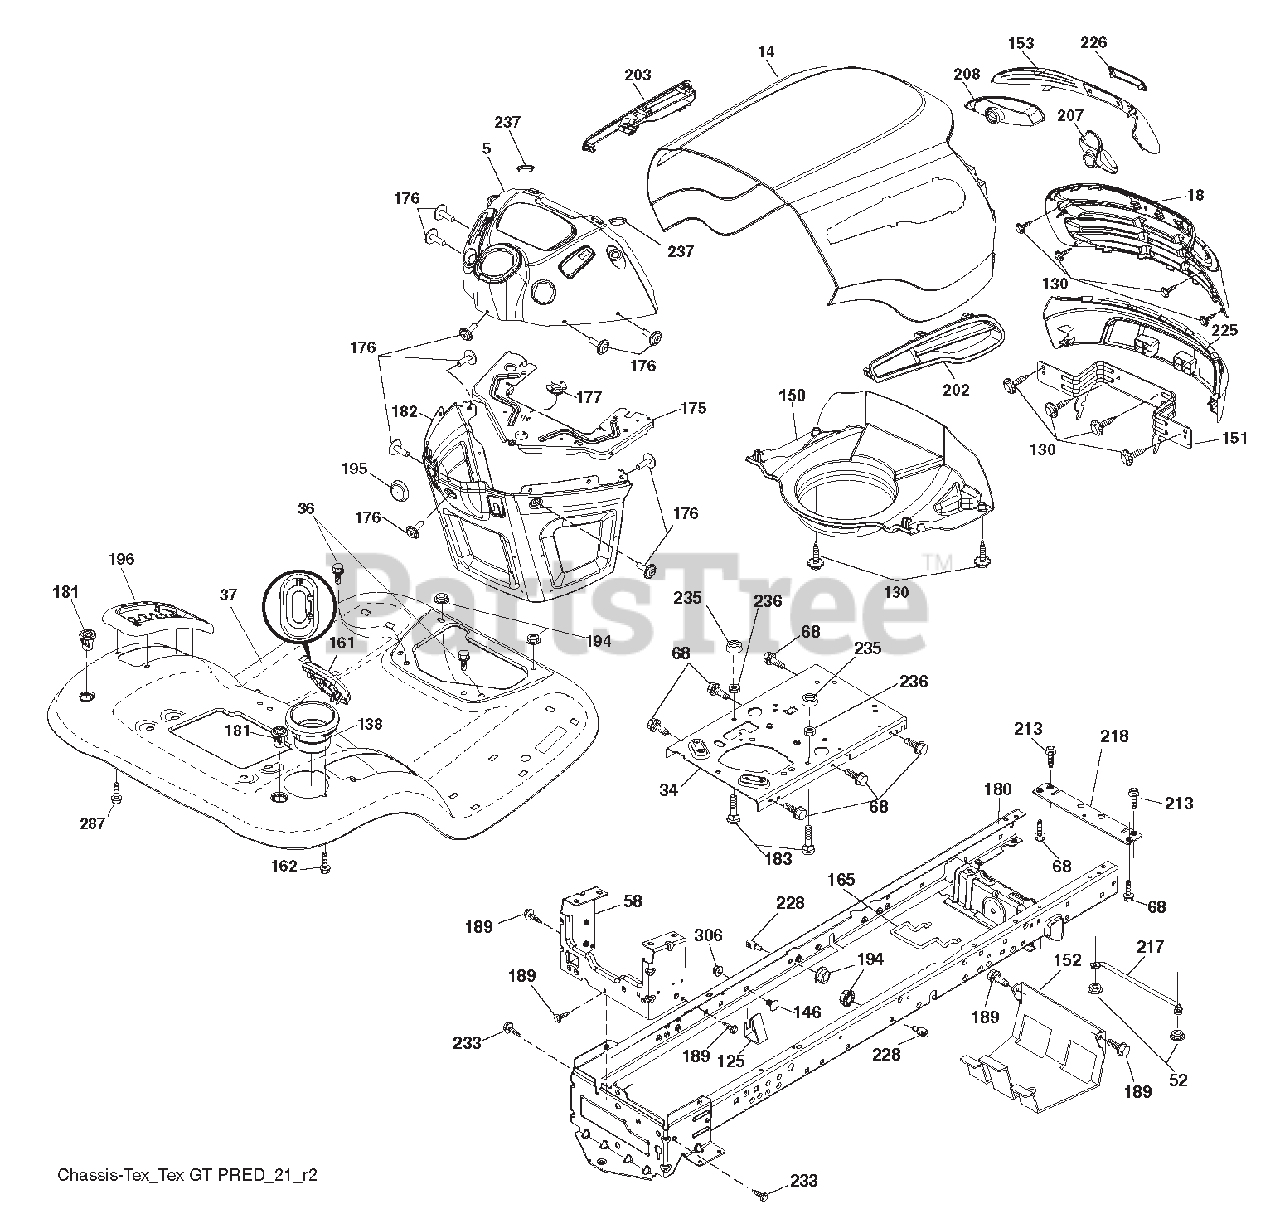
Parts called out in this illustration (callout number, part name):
5	DASH P/L TEX CABLE
18	GRILLE.ELITE.ARIENS.BLACK
34	PLATE.ENGINE.WELDED.CHASSIS
36	SCREW.5/16-18X3/4.SMGML.TAP/R
52	Nut, Hex, Crownlock 5/16-18
58	DRAWBAR.UPPER.2PC.SML.FENDER
68	SCREW.THDROL.5/16-18 X 1/2TYTT
125	CLIP.FUEL.LINE
138	CUPHOLDER TL TEX 428
150	AIR DUCT
151	BRACKET.PIVOT
152	SHIELD.BROWNING.W/TEX
153	LENS.BAR
161	WINDOW FUEL
162	SCREW.HEX.WSH.HI-LO.1/4X1/2UNC
165	SUPPORT.TANK.REAR.W/TEX
175	CROSSMEMBER.LT
176	SCREW.#10-24X5/8.RND.QUDRX.GIM
177	BUSHING.STEERING.YT/GT
180	CHASS.WLDMT.TL.12GA/2PC.18/22"
181	BUSHING MNT FEND CRGO BLK TEX
182	DASH.LOWER.LT.CCS
183	BOLT.FIN.HEX.5/16-18 UNC X1-1/
189	SCREW.5/16-18X3/4.SMGML.TAP/BL
194	Nut, Lock Hex Flange 5/16-18 u
195	PLUG HOLE DASH TOWER
196	CONSLE.ASM.DECK.LFT.BL/RBT.TLT
202	VENT RH
203	VENT.SIDE.LH
207	BEZEL.RH
208	BEZEL.LH
213	BOLT.HEX.HD.1/4-20UNC X 3/4
217	ROD.PIVOT.HOOD
218	X-PIECE.HOOD.STOP.NON/STEALTH
226	ARIENS.LOGO.PLATE
228	STUD.FASTNER.W/'D'ANTI-ROTATIO
233	BOLT.SHOULDER
235	SPACER.FENDER
236	NUT.CENTER LOCK.5/16-18 UNC
237	PLUG.MOUNT.CARGO
287	SCREW.HEX.WASHEAD.1/4-20 X 3/8
306	Nut, Hex, Flangelock 3/8-16
